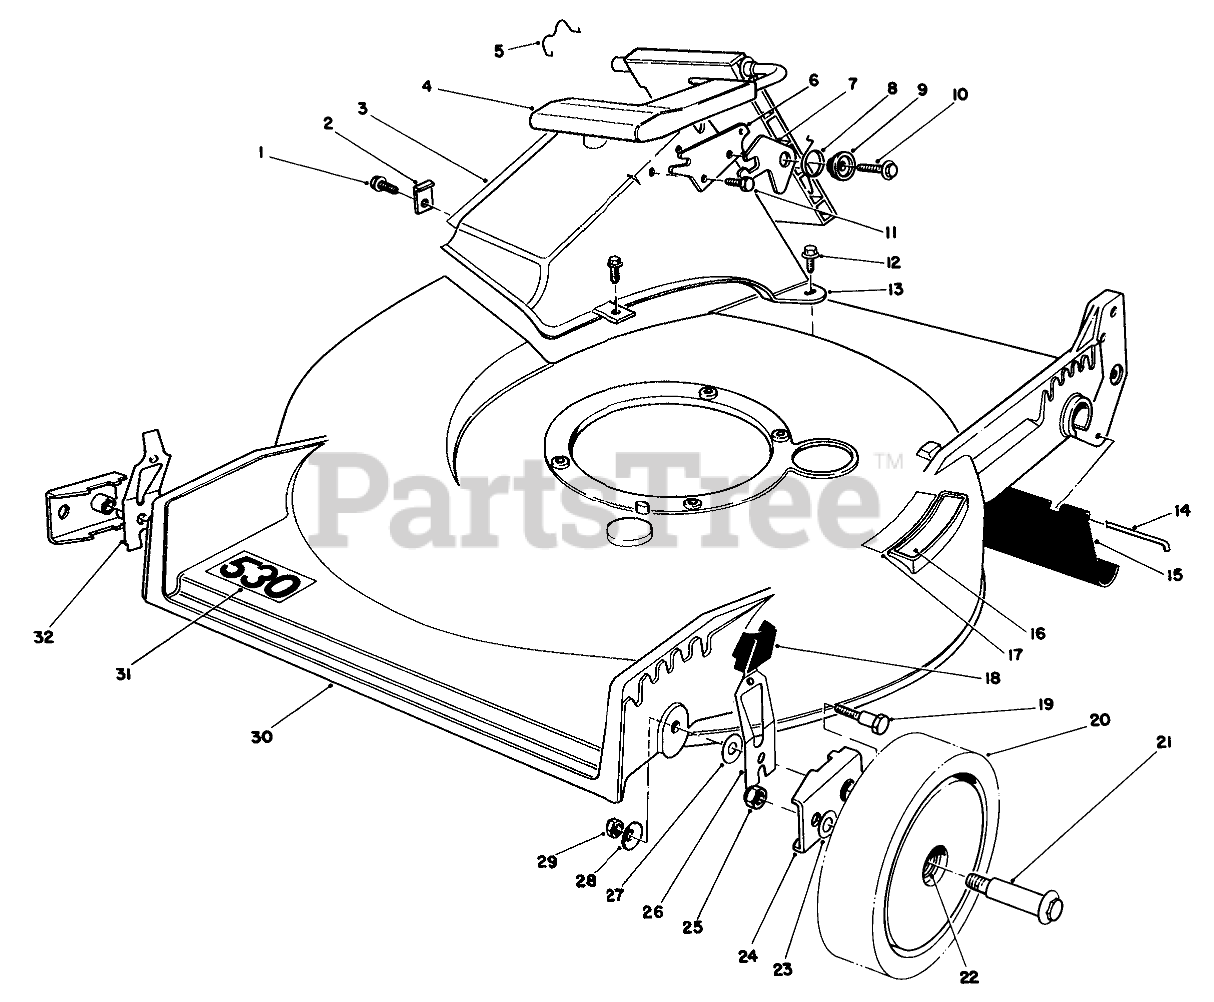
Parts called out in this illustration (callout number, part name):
1	SCREW
2	TUNNEL CLIP
3	Decal-Attention
4	Discharge Door Assembly
5	DOOR RET SPRING
6	DOOR LATCH PLATE
7	SAFETY LATCH
8	TORSION SPRING
9	DOOR SPACER
10	SCREW-HWH
11	SCREW-PLASTITE
12	SCREW-HWH
13	Tunnel Discharge
14	ROD-SHIELD
15	SHIELD-TRAILING
16	STEP PAD DECAL
17	Decal-Place Foot Here
18	KNOB-ARM
19	PIVOT SCREW
20	Wheel & Tire Assembly (Incl. Ref. #22)
21	WHEEL BOLT
22	BUSHING
23	WASHER
24	HP PIVOT ARM ASM
25	NUT-LOCK
26	L. HP SPRING ARM ASM
27	WASHER-PIVOT
28	WASHER-BELLEVILLE
29	NUT-LOCK, NI
30	21HP RB-SUZ HSG/DECAL
31	Decal-530
32	R HP SPRING ARM ASM
